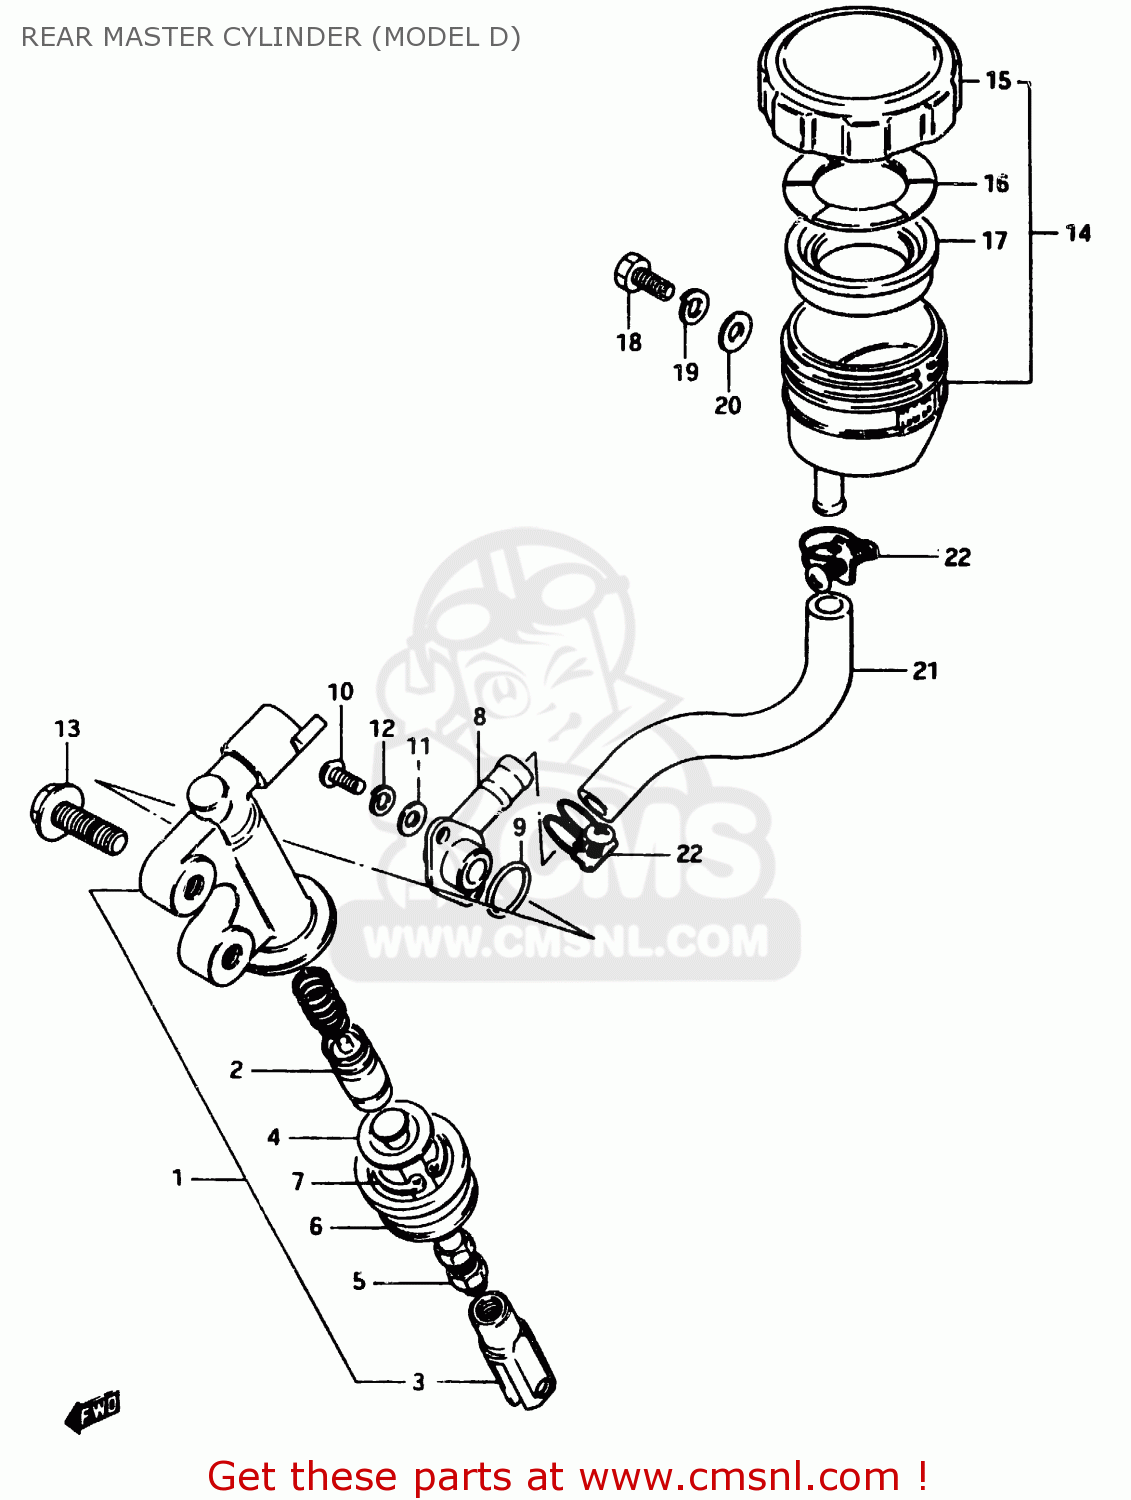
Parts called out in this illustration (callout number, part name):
1	CYLINDER ASSY,RR MASTER
2	PISTON/CUP SET
3	YOKE
4	ROD,PUSH
5	NUT,MASTER CYLINDER
6	BOOT
7	CIRCLIP
8	CONNECTOR,HOSE
9	O RING
10	SCREW
11	WASHER
12	LOCK WASHER
13	BOLT
14	TANK ASSEMBLY,RESERVOIR
15	CAP
16	PLATE,DIAPHRAGM
17	DIAPHRAGM
18	SCREW(6X12)
19	LOCK WASHER
20	WASHER
21	HOSE,RESERVOIR TANK
22	CLAMP
